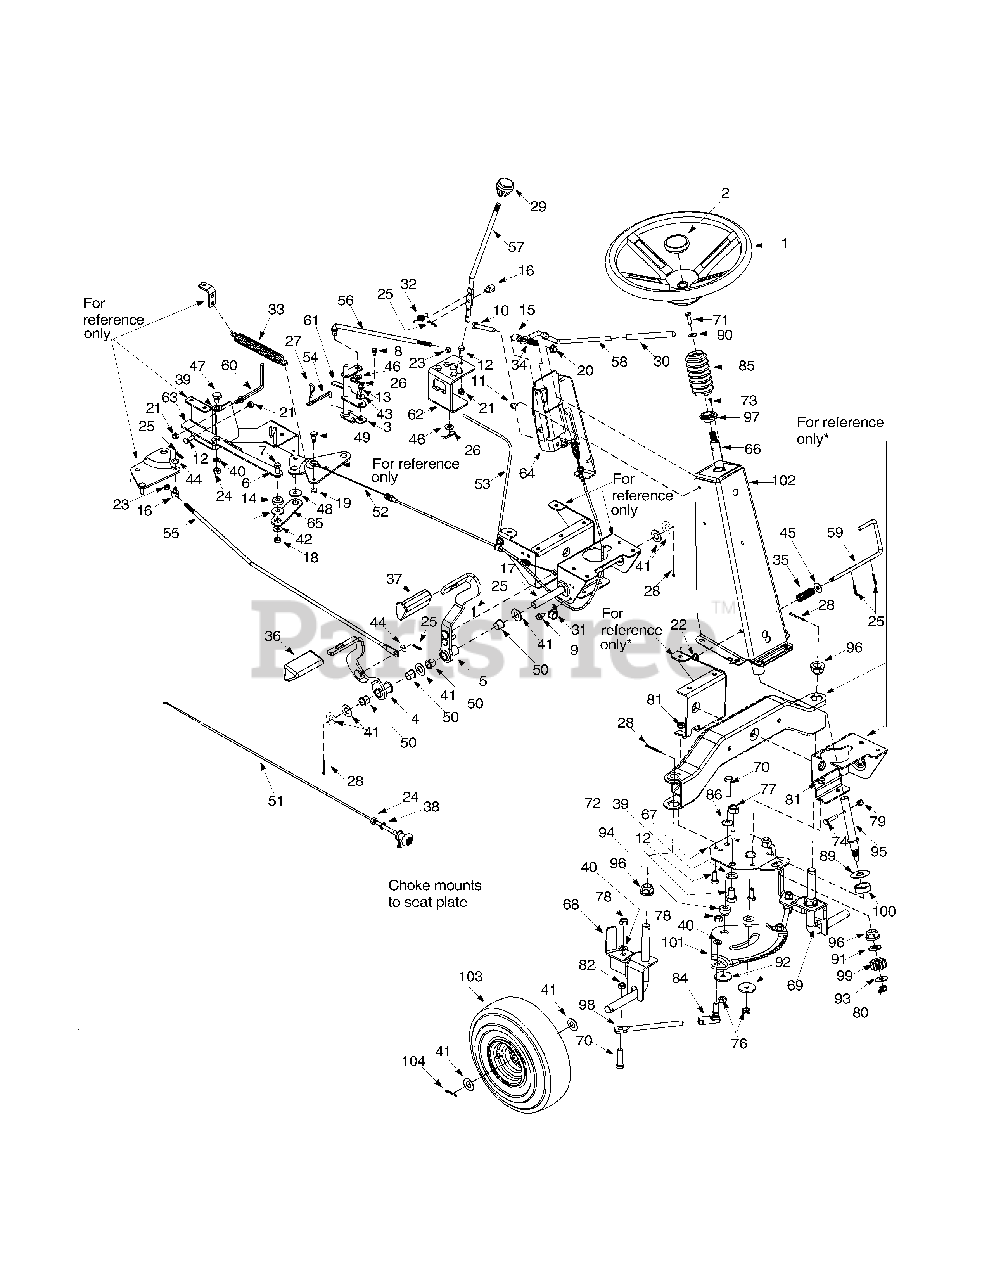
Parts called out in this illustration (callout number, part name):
1	Steering Wheel
2	Steering Wheel Cap
3	Shift Pivot Assembly
6	Idler Brake Assembly
7	Hex Bolt 3/8-24 x 1.25"
8	TT Screw 1/4-20 x 0.5"
9	TT Screw 5/16-18 x 0.625"
10	Hex Bolt 3/8-16 x 2.5"
11	AB Screw 1/4-14 x 0.625"
12	Hex Bolt
13	Hex Bolt 1/4-20 x 0.50"
14	Spacer
15	Spacer
16	Ferrule
17	Shaft
18	Jam Nut 3/8-24
19	Flange Lock Nut 1/4-28
20	Flange Lock Nut 3/8-16
21	Nylon Lock Nut
22	Flange Lock Nut 5/16-18
23	Jam Nut 5/16-18
24	Hex Nut 3/8-16
25	Cotter Pin
26	Click Pin
27	Hairpin Clip
28	Cotter Pin
29	Shift Knob
30	Clutch Grip
31	Clamp
32	Extension Spring
33	Extension Spring
34	Compression Spring
35	Compression Spring
36	Drive Pad
37	Brake Pad
38	Lock Washer
39	Flat Washer.53 x 1.0 x .032
40	Lock Washer 3/8
41	Flat Washer
42	Flat Washer
43	Bell Washer
44	Thrust Washer
45	Flat Washer
46	Flat Washer
47	Shoulder Screw .50 x .21: 3/8-16
48	Shoulder Spacer
49	Shoulder Screw 1/4-28 x .375
50	Flange Bearing
51	Choke Control
52	Deck Cable
53	Brake Cable
54	Shift Rod
55	Variable Control Rod
56	Control Rod
57	Shift Rod
58	PTO Lever
59	Brake Lock -Out Rod
60	Belt Keeper Rod
61	Shift Switch Bracket
62	Shift Index Bracket
63	Brake Mounting Bracket
64	Cont. Bracket: PTO
65	Link Bracket
66	Steering Tube Assembly
67	Steering Support Bracket
68	Front Axle RH
69	Front Axle LH
70	Hex Bolt 3/8-24 x 1.5"
71	Hex Bolt 5/16-18 x 1.0"
72	Hex Bolt 1/2-13 x 0.75"
73	AB Screw #10-16 x 0.625"
74	Hex Bolt 1/4-20 x 1.25"
76	Jam Lock Nut 3/8-24
77	Hex Nut 1/2-13
78	Hex Nut 3/8-24
79	Hex Lock Nut 1/4-20
80	Hex Lock Nut 5/16-24
81	Hex Lock Nut
82	Jam Nut
84	Ball Joint 3/8-24
85	Steering Bellow
86	Bell Washer
89	Flat Washer.628 x 1.56 x .036
90	Bell Washer .340 x .872 x .060
91	Flat Washer .510 x 1.0 x .060
92	Flat Washer 3/8 x 1.37
93	Flat Washer .344 x 1.0 x .063
94	Spacer
95	Steering Adapter
96	Hex Flange Bearing
97	Bearing: Steering Column
98	Tie Rod
99	Pinion Gear
100	Spacer
101	Steering Gear
103	Fl. Bearing
103	Fl. Bearing w/Fitting
104	Cotter Pin
